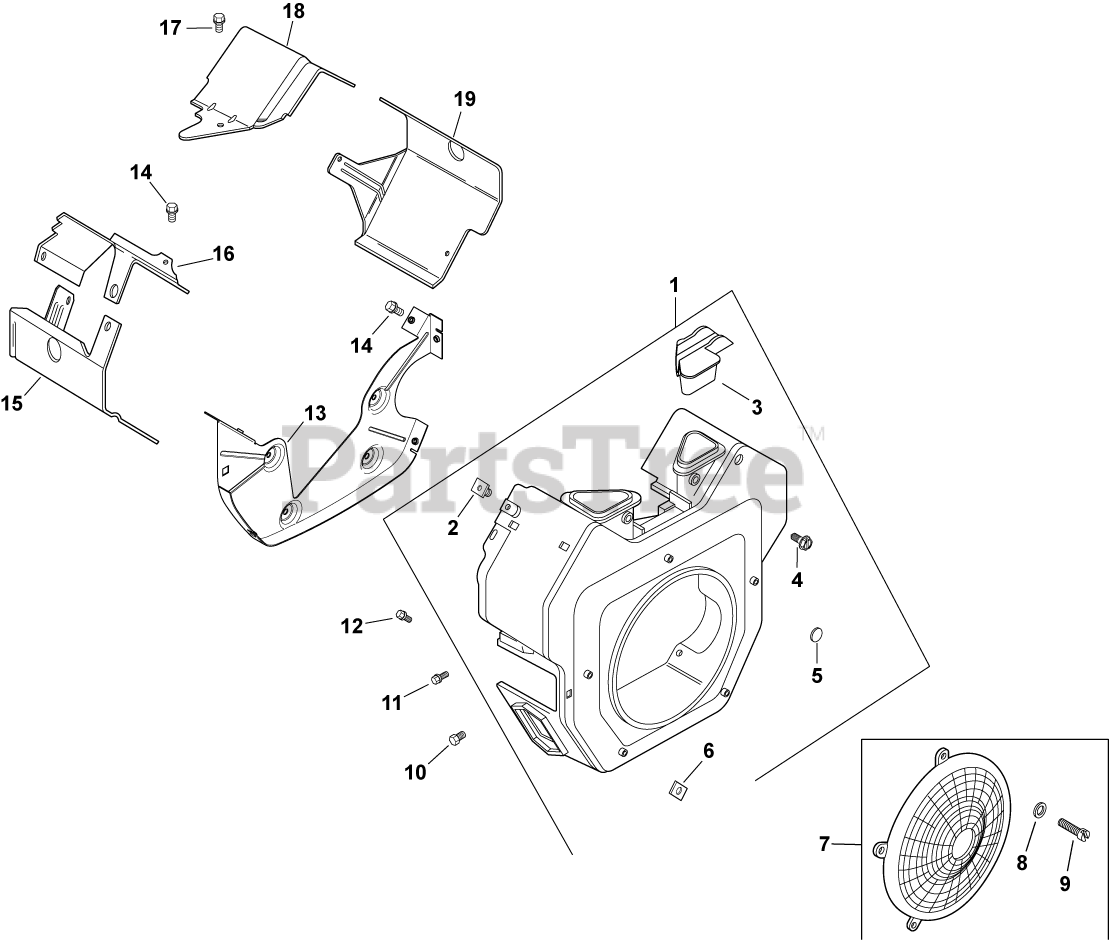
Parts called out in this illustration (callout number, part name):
1	KIT, BLOWER HOUSING ASSEMBLY
2	NUT, PLASTIC (KM)-USE 25 100 37-S
3	COVER, BLOWER HOUSING-USE 24 096 119-S
4	SCREW, WSH HD TAP #8-18X1/2"
5	PLUG, BUTTON 9/16
6	NUT, PLASTIC
7	KIT, FIXED GUARD
8	WASHER, FLAT 7/32"
9	SCREW, LBD SCKT PAN M5X0.8X10
10	SCREW, HVY FLG M5X.8X16
11	SCREW,FLG THD FRM M5X0.8X16-(#25086398S)
12	SCREW, FLG THD FRM M5X.8X20-(#25086399S)
13	PLATE, BACKING (OIL COOLER)-USE 24 146 5
14	SCREW,FLG THD FRM M6X1.0X16-(#25086397S)
15	BAFFLE,VALLEY #2SIDE(KM)-USE 24 063 88-S
16	BAFFLE, VALLEY #2 SIDE-USE 24 063 94-S
17	SCREW, HVY FLG M5X.8X10
18	BAFFLE, VALLEY (CH)-USE 24 063 93-S
19	BAFFLE, RIGHT BARREL-USE 24 063 85-S
